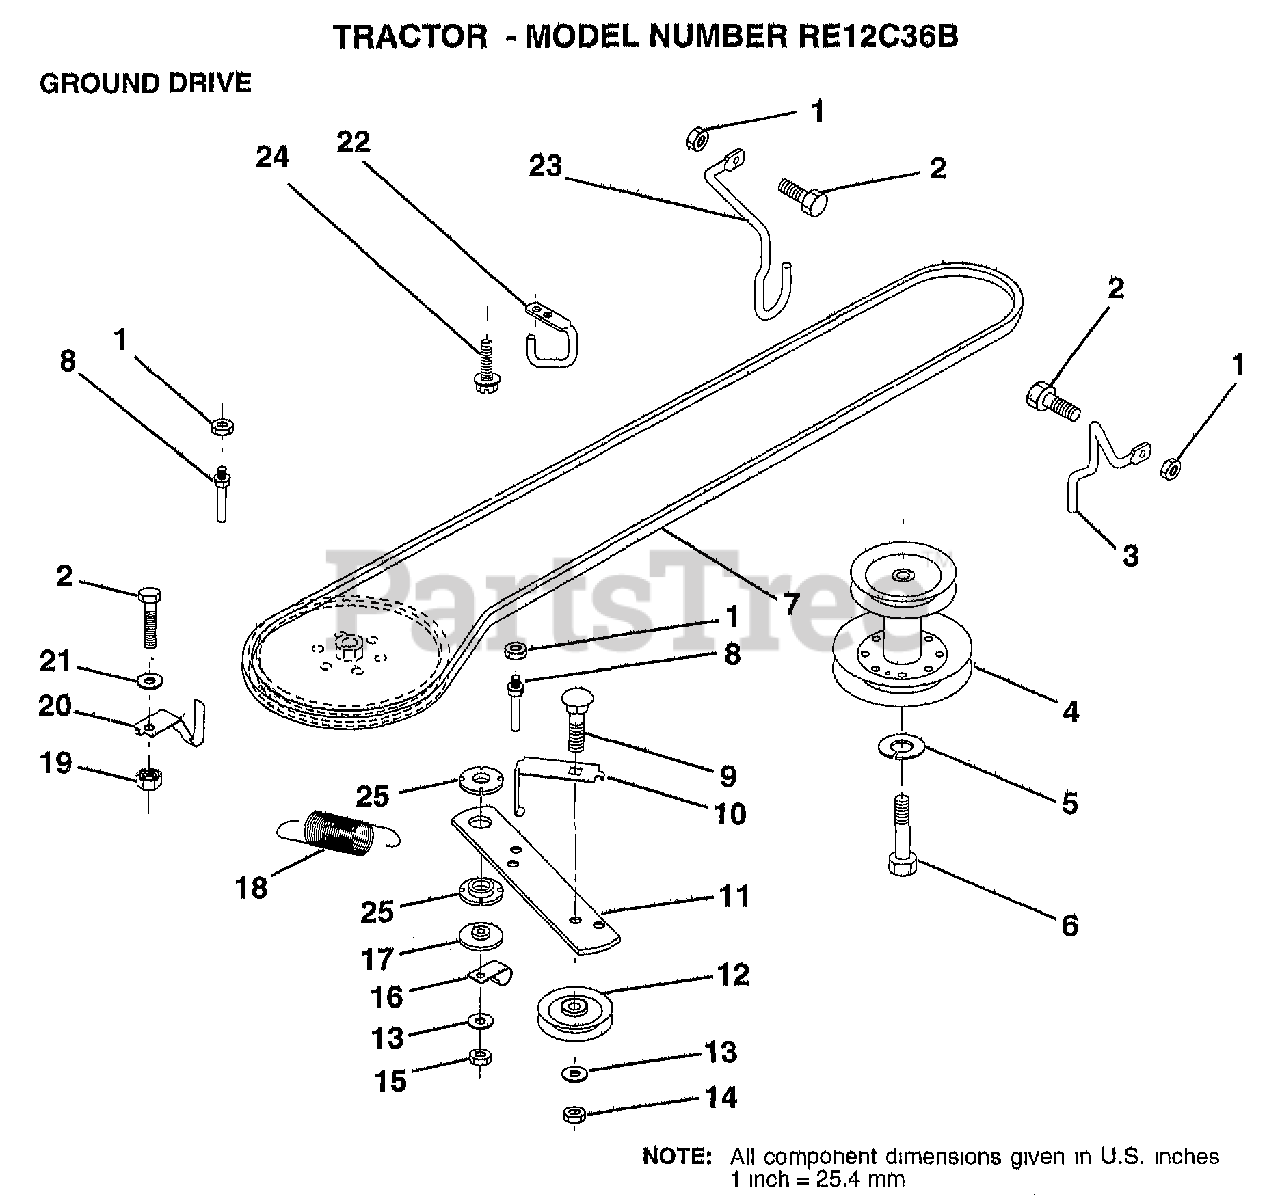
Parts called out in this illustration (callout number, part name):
2	BOLT
3	KEEPER RH
4	PULLEY.ENGINE.LR
5	LOCKWASHER
6	HEX BOLT
7	V BELT
8	"KEEPER,DRIVE BELT"
9	BOLT
10	"KEEP,IDLER DR BEL"
11	ARM-IDLER.DR.GRND
12	PULLEY.IDLER.FLAT
13	WASHER
14	LOCKNUT
16	"CLIP,INSULATOR"
17	SPACER
20	KEEPER.BELT.T/A
21	WASHER
22	"KEEPER,FRA DR BEL"
23	KEEPER MOWER LH
24	SCREW
25	BUSHING.NYLON
